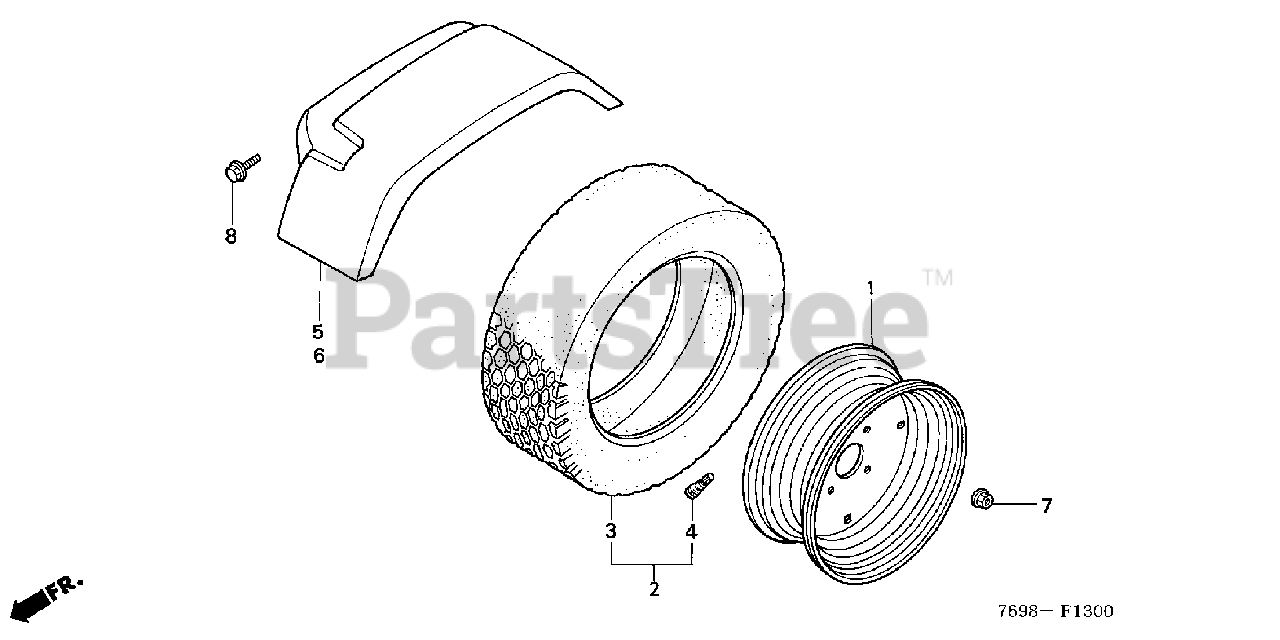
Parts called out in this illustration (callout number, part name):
1	WHEEL (12X5JA) (WDC)
1	WHEEL (14X6JJ)
2	TIRE ASSY., RR. (24X8.00-14) (2PR) (OHTSU)
3	TIRE, RR. TUBELESS (7-12-4PR)
4	VALVE, RIM
5	FENDER, R. RR. *R165* (JOLLY RED)
5	FENDER, R. RR. *R280* (POWER RED)
6	FENDER, L. RR. *R280* (POWER RED)
7	NUT, WHEEL (12MM)
8	BOLT, FLANGE (8X16)
